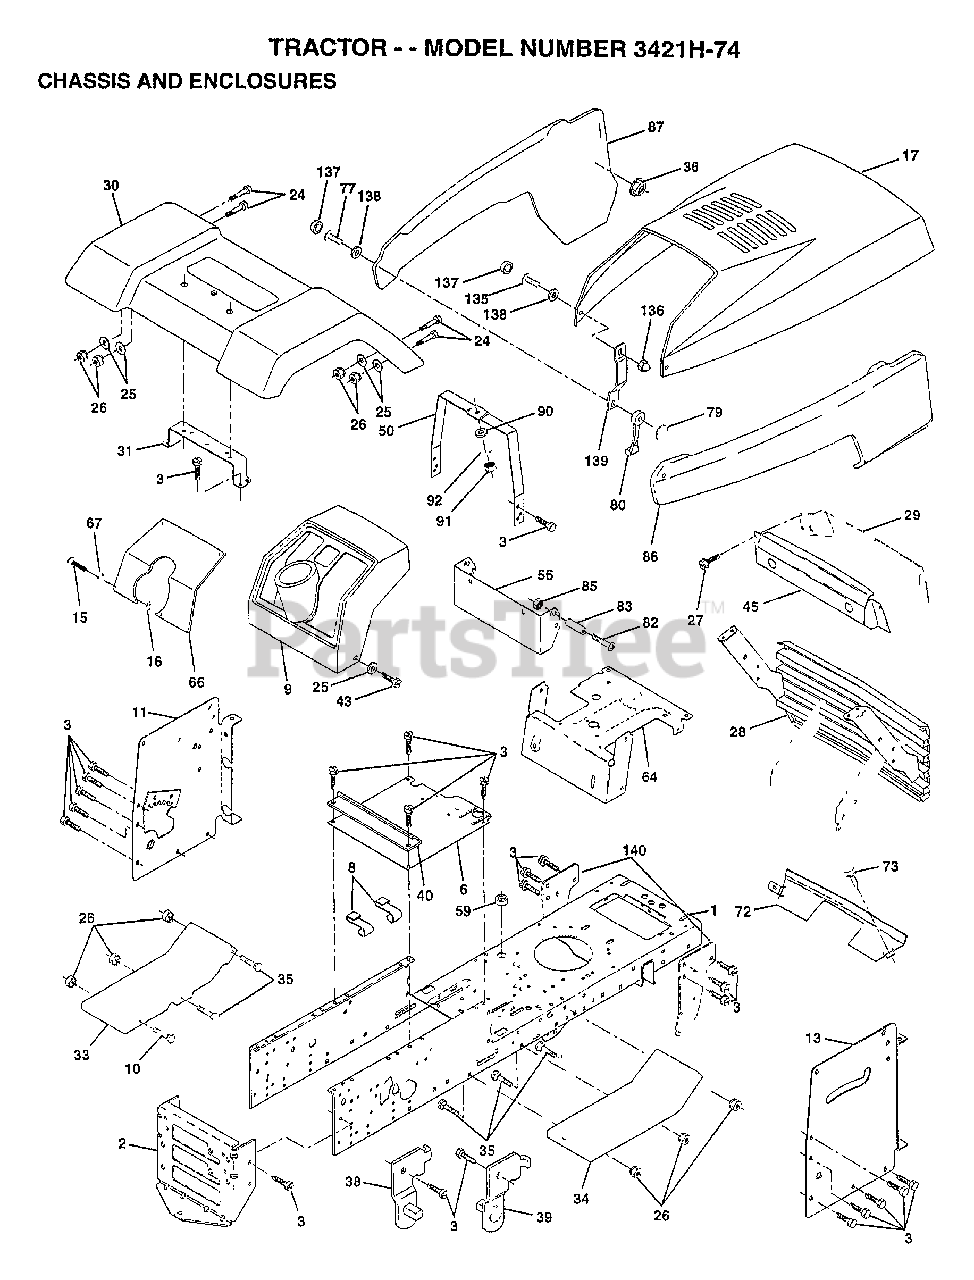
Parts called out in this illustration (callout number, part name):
1	CHASSIS ASM
3	SCREW
6	SADDLE
8	"CLIP,INSULATOR"
9	DASHBOARD BLACK
11	PANEL.DASH.LH.
13	PANEL.DASH.RH.
15	SCREW
24	BOLT
25	WASHER
26	NUT
28	GRILLE ASM PNT
29	LENS.BAR.CLEAR
31	BRACKET SUPT FEND
33	FOOTREST.LH.LT/GT
34	FOOTREST.RH.LT/GT
35	BOLT
36	PAL NUT LT
38	BRACKET ASM LH
39	BRACKET ASM RH
40	SPACER FENDER LT
43	SCREW GTV
45	BEZEL.ASM.
50	DASH.SUPT.YP/HUSQ
56	EXT DASH LTYT
64	DASH.LOWER.LT
66	"PLATE DASH,SLKSCR"
67	WASHER
72	STRAP.GRILLE.424
73	SCREW CRT
77	SCREW
79	WELDNUT
80	HOOD LATCH T
82	SCREW
83	SPACER LT
90	WASHER PM
92	LOCKWASHER
135	SCREW.10-24X3/8.
136	ACORN NUT RB
137	SNAP CAP LT
138	WASHER LT
139	BKT.SPT.HOOD/PANL
140	BRKT SUSPENSION
